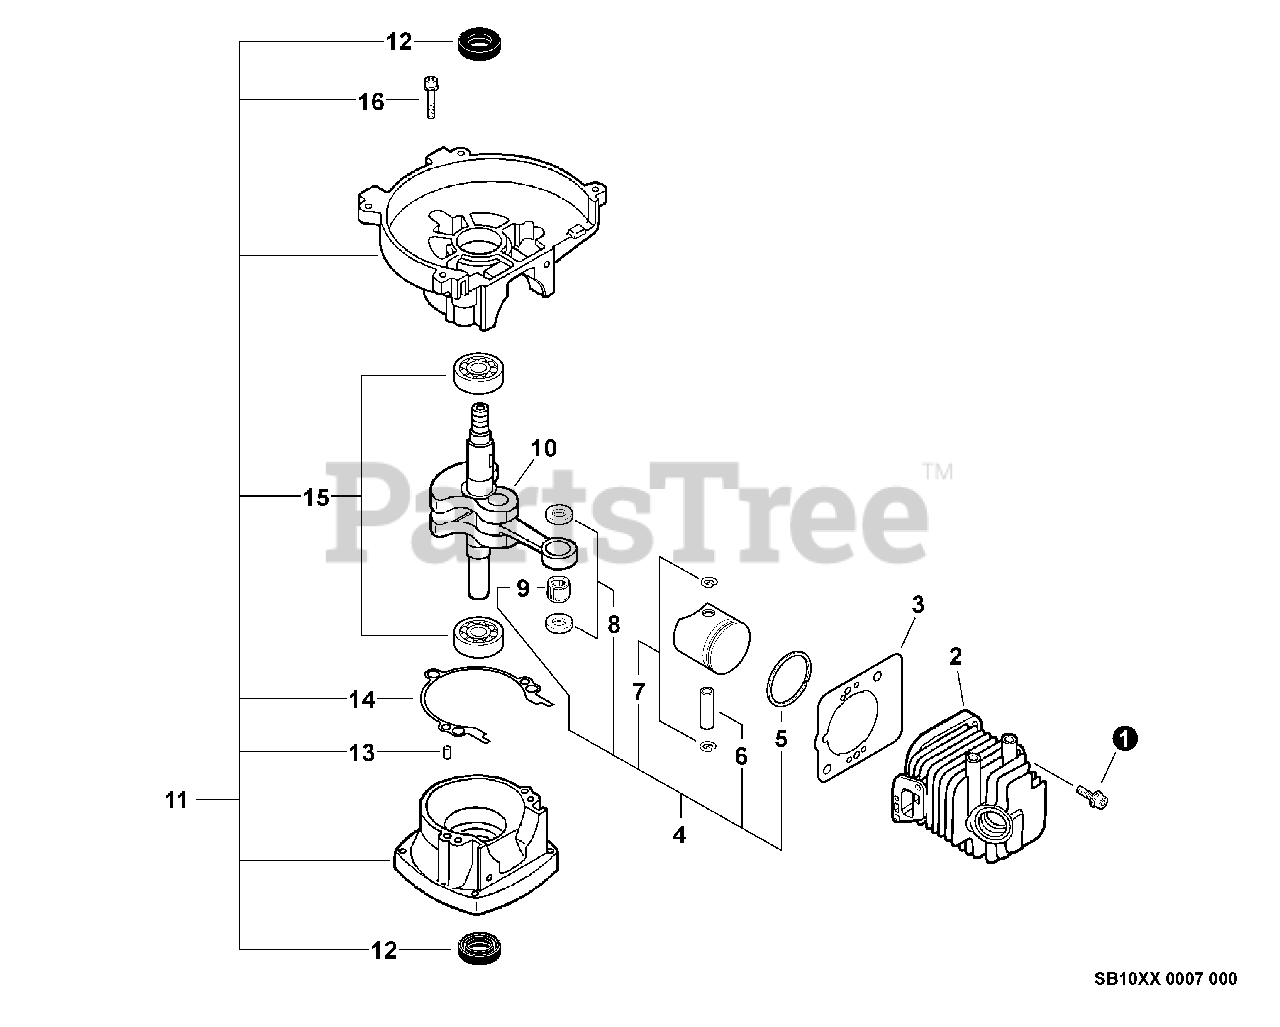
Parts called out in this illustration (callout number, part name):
1	SCREW - 5X22
2	CYLINDER
3	GASKET, CYLINDER
4	PISTON KIT
5	RING, PISTON
6	PIN, PISTON
7	RING, RETAINING
9	BEARING, NEEDLE - 8
10	CRANKSHAFT ASSY
11	CRANKCASE KIT
12	SEAL, OIL
13	PIN - LOCATING
14	GASKET, CRANKCASE
15	BEARING, BALL - 6201
16	SCREW - 5X28
